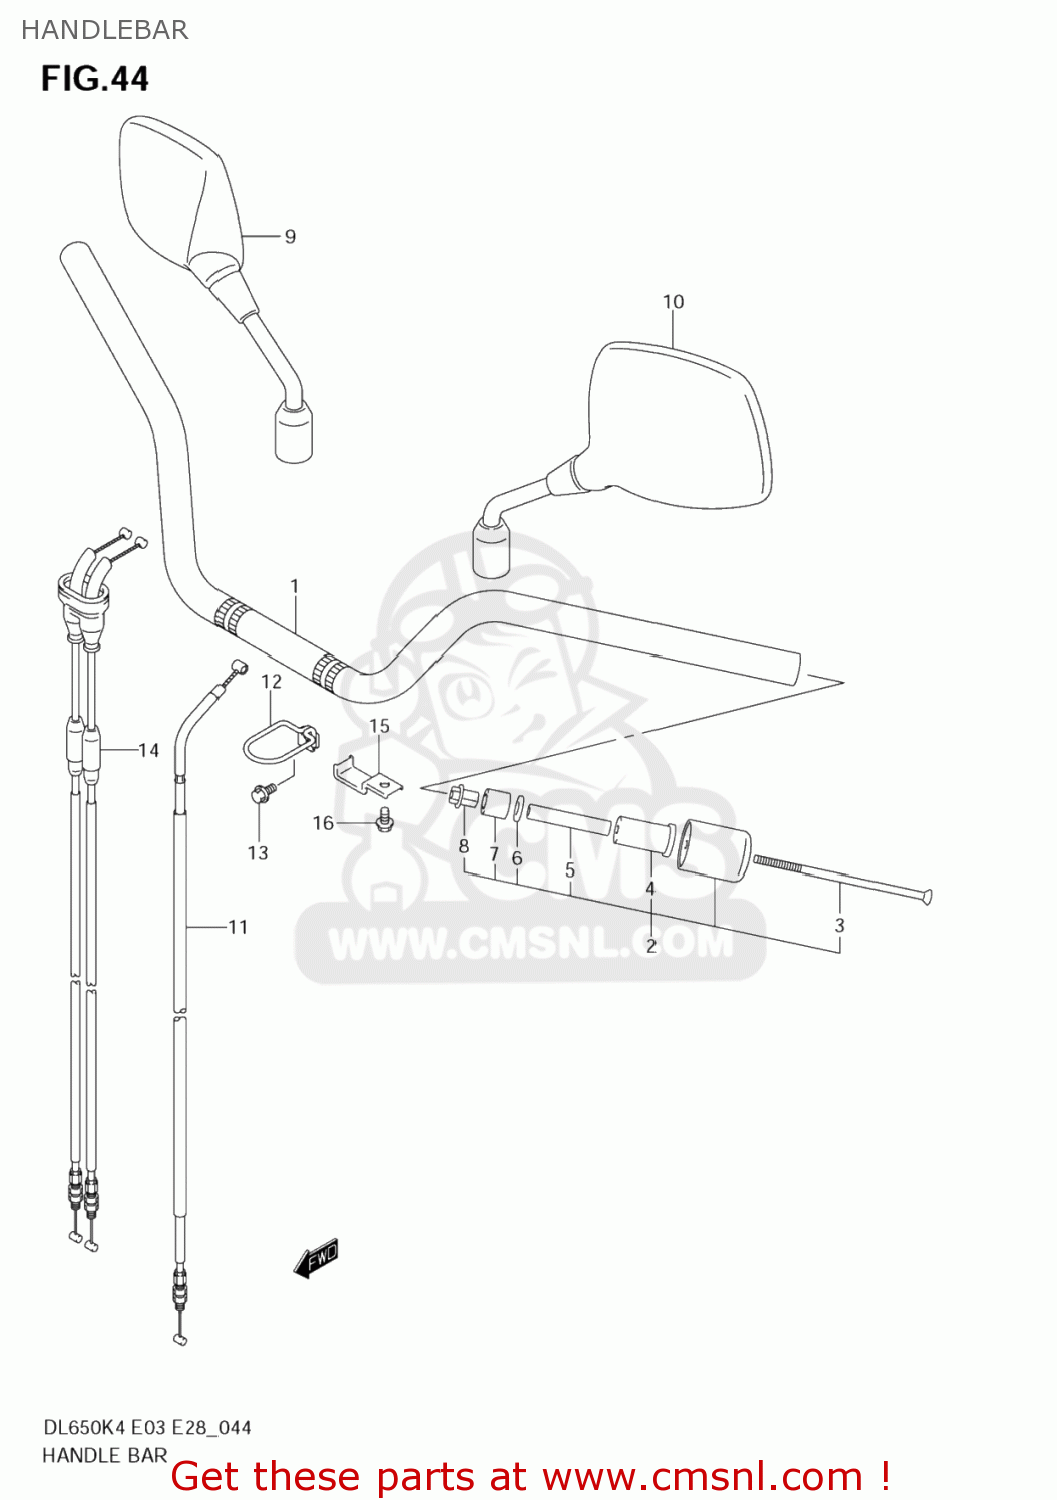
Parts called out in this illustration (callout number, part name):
1	HANDLEBAR
2	BALANCER SET,H
3	SCREW(6X110)
4	EXPANDER
5	SPACER,EXPANDER
6	WASHER(6.5X16X4)
7	EXPANDER,HANDLE BALANCER
8	NUT,HANDLE BAL
9	MIRROR ASSY,RH
10	MIRROR ASSY,LH
11	CABLE ASSY,CLUTCH
12	GUIDE COMP,CLU
13	BOLT
14	CABLE ASSY,THROTTLE
15	GUIDE,THROTTLE CABLE
16	BOLT
